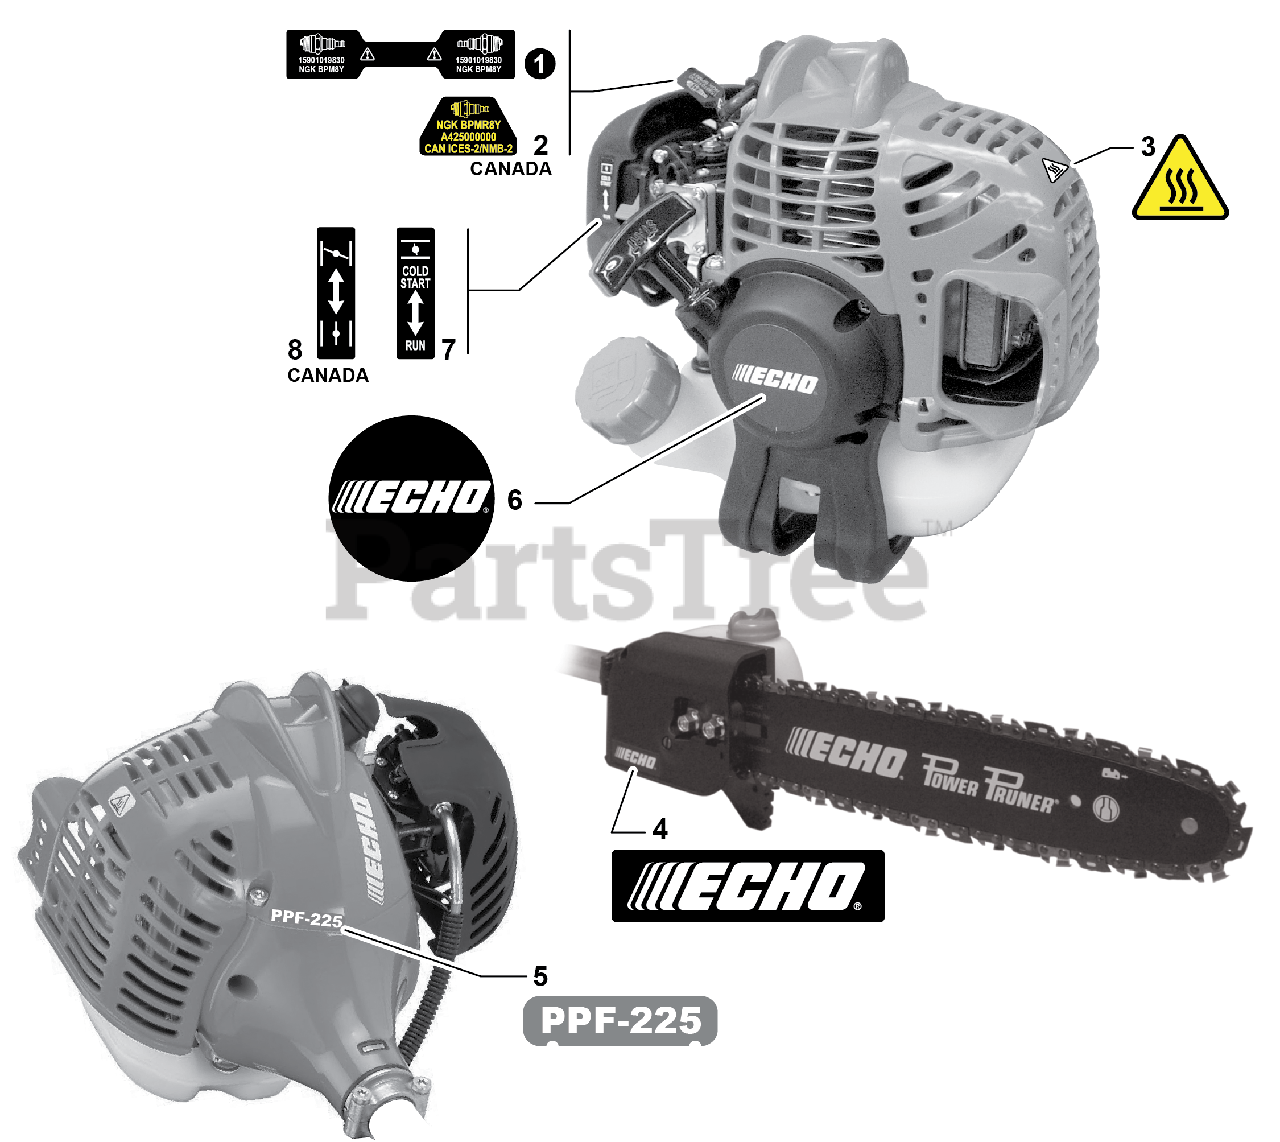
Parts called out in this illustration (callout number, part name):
1	LABEL, SPARK PLUG - BPM8Y
2	LABEL, SPARK PLUG - BPMR8Y
3	LABEL, CAUTION - HOT
4	LABEL, ECHO
5	LABEL, MODEL PPF-225
6	LABEL, RECOIL STARTER
7	LABEL, CHOKE
8	LABEL, CHOKE
